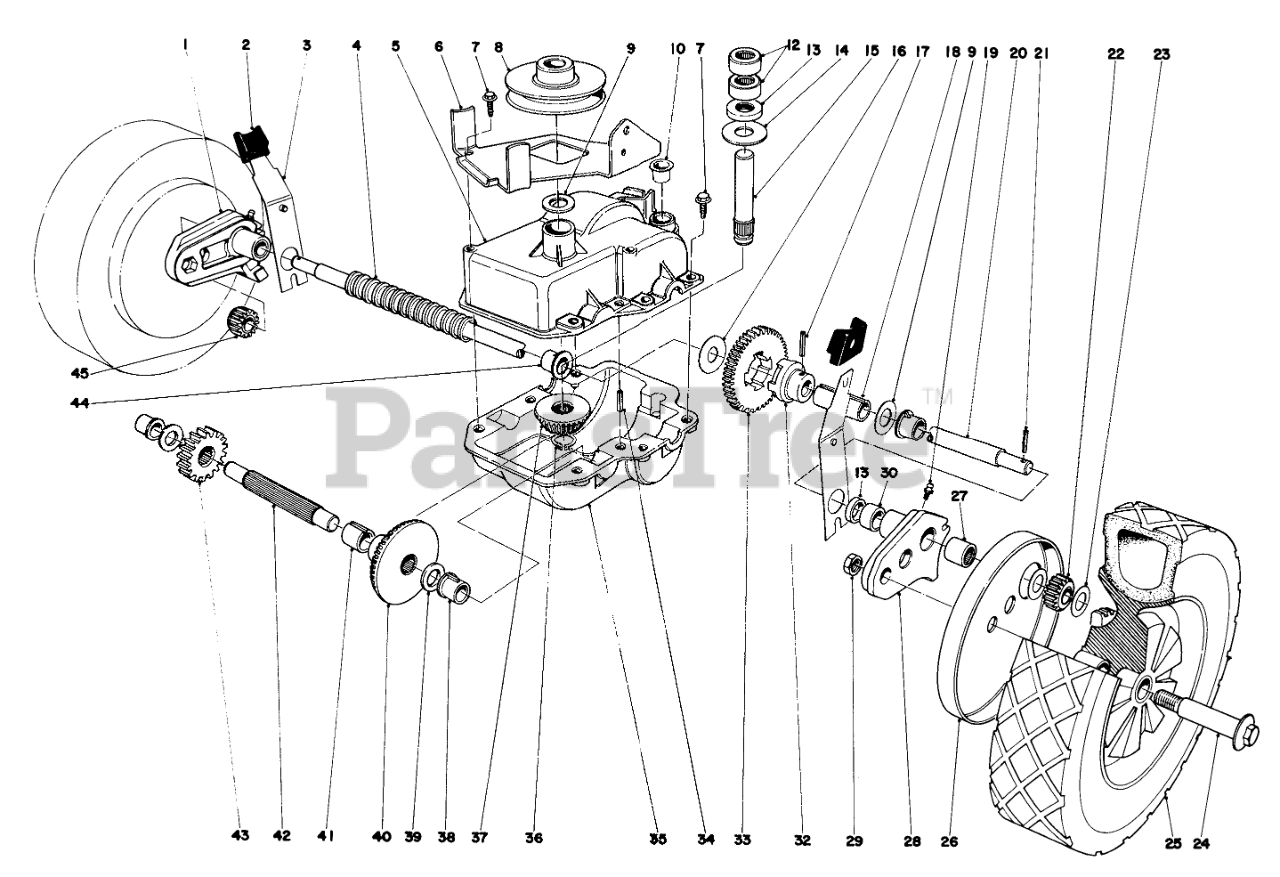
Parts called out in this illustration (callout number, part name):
1	Pivot Arm R.H (Incl. Ref. #19, 27 & 30-31)
2	KNOB-ARM
3	SP SPRING ARM ASM
4	Cover Drive Shaft
5	Case Upper
6	Bracket-Belt Guide
7	Screw
8	Pulley
9	WASHER-PLAIN
10	Caplug
12	Bearing
13	Seal
14	Thrust Washer
15	Input Shaft & Pully Assembly (Incl. Ref. #8)
16	WASHER
17	COIL PIN
18	Spacer-Output Shaft
19	FITTING-GREASE
20	OUTPUT SHAFT
21	Pin
22	Pinion Gear
23	WASHER
24	BOLT-WHEEL
25	Wheel & Tire Assembly
26	Cover-Wheel
27	Needle Baring
28	Pivot Arm L.H. (Incl. Ref. #19, 27 & 30-31)
29	Nut
30	Bushing
32	ADAPTER DRIVE
33	Gear
34	ROLL PIN 3/16 X 1 IN
35	LOWER GEAR CASE CAST
36	RING-RETAINING
37	Pinion Bevel
38	Botching Shaft
39	WASHER-THRUST
40	Bevel Gear
41	Shaft-Pivot
42	Short Shaft
44	Bushing
45	Pinion Gear
